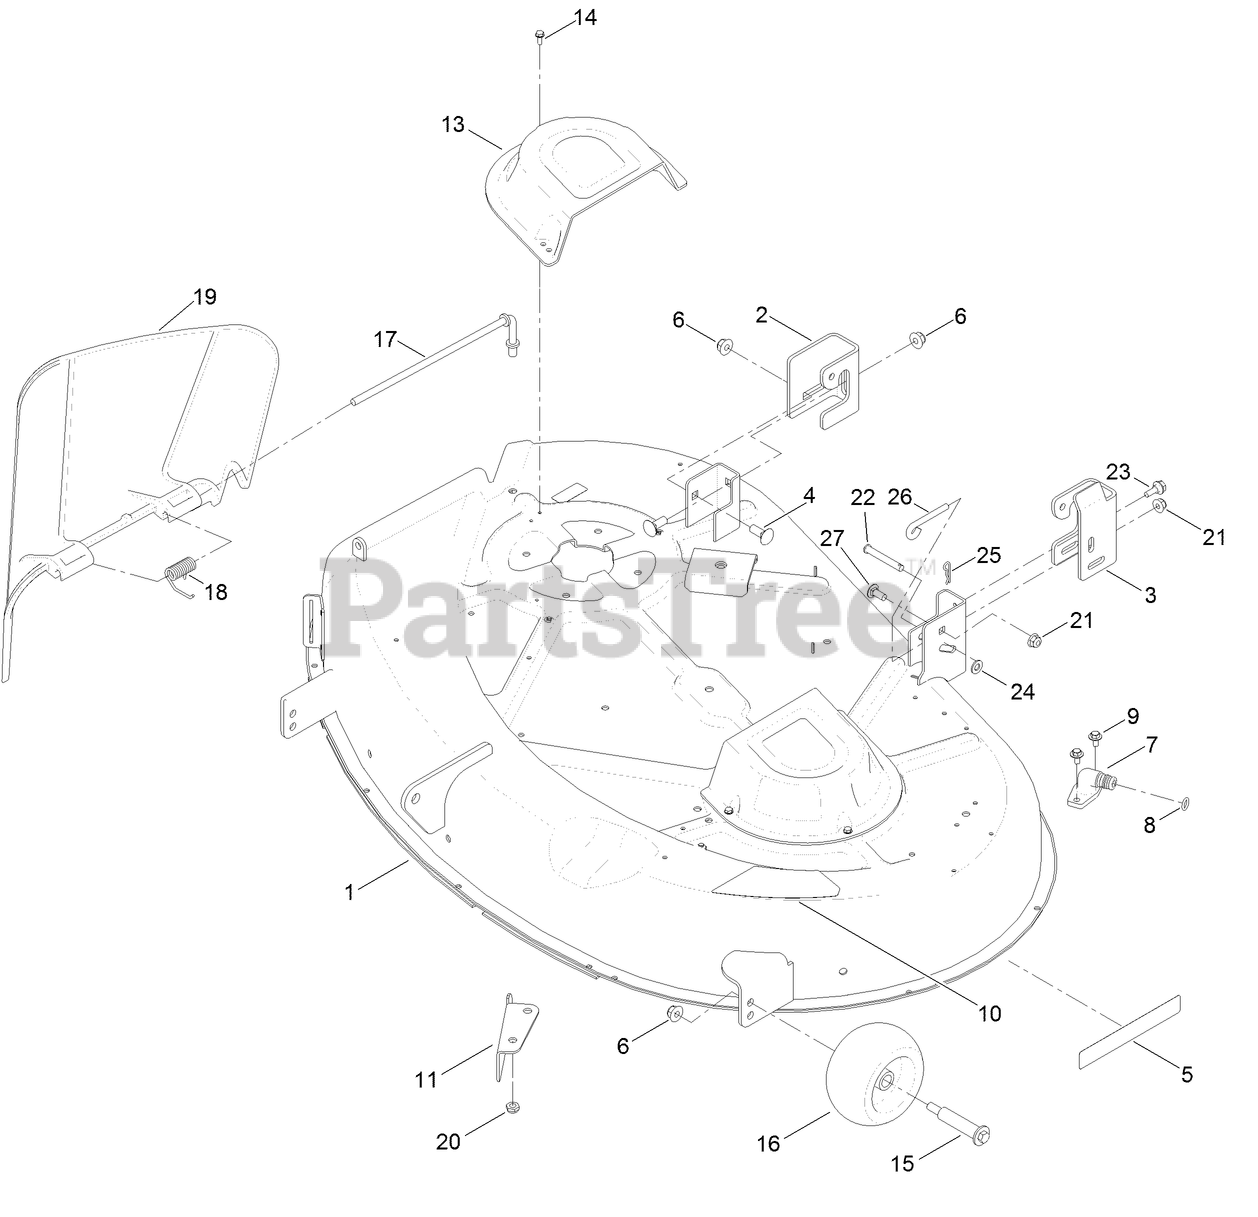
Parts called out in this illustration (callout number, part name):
1	42 INCH DECK AND DECAL ASM
2	BRACKET-HANGER, RH
3	BRACKET-HANGER, LH
4	BOLT-CARR
5	DECAL-RECYCLER
6	NUT-HF, NI
8	O-RING
9	SCREW-HHFTF
11	BAFFLE-CUTOFF
13	COVER-BELT
14	SCREW-TAPTITE
15	BOLT-SHOULDER
16	ROLLER-SCALP, ANTI
17	ROD-PIVOT
18	SPRING-TORSION
19	DEFLECTOR
21	NUT-HF, NI
22	PIN-CLEVIS
23	SCREW-SHOULDER,HWH
24	WASHER-PLAIN
25	PIN-COTTER
26	ROD-LEVEL, DECK
27	SCREW-CARR
